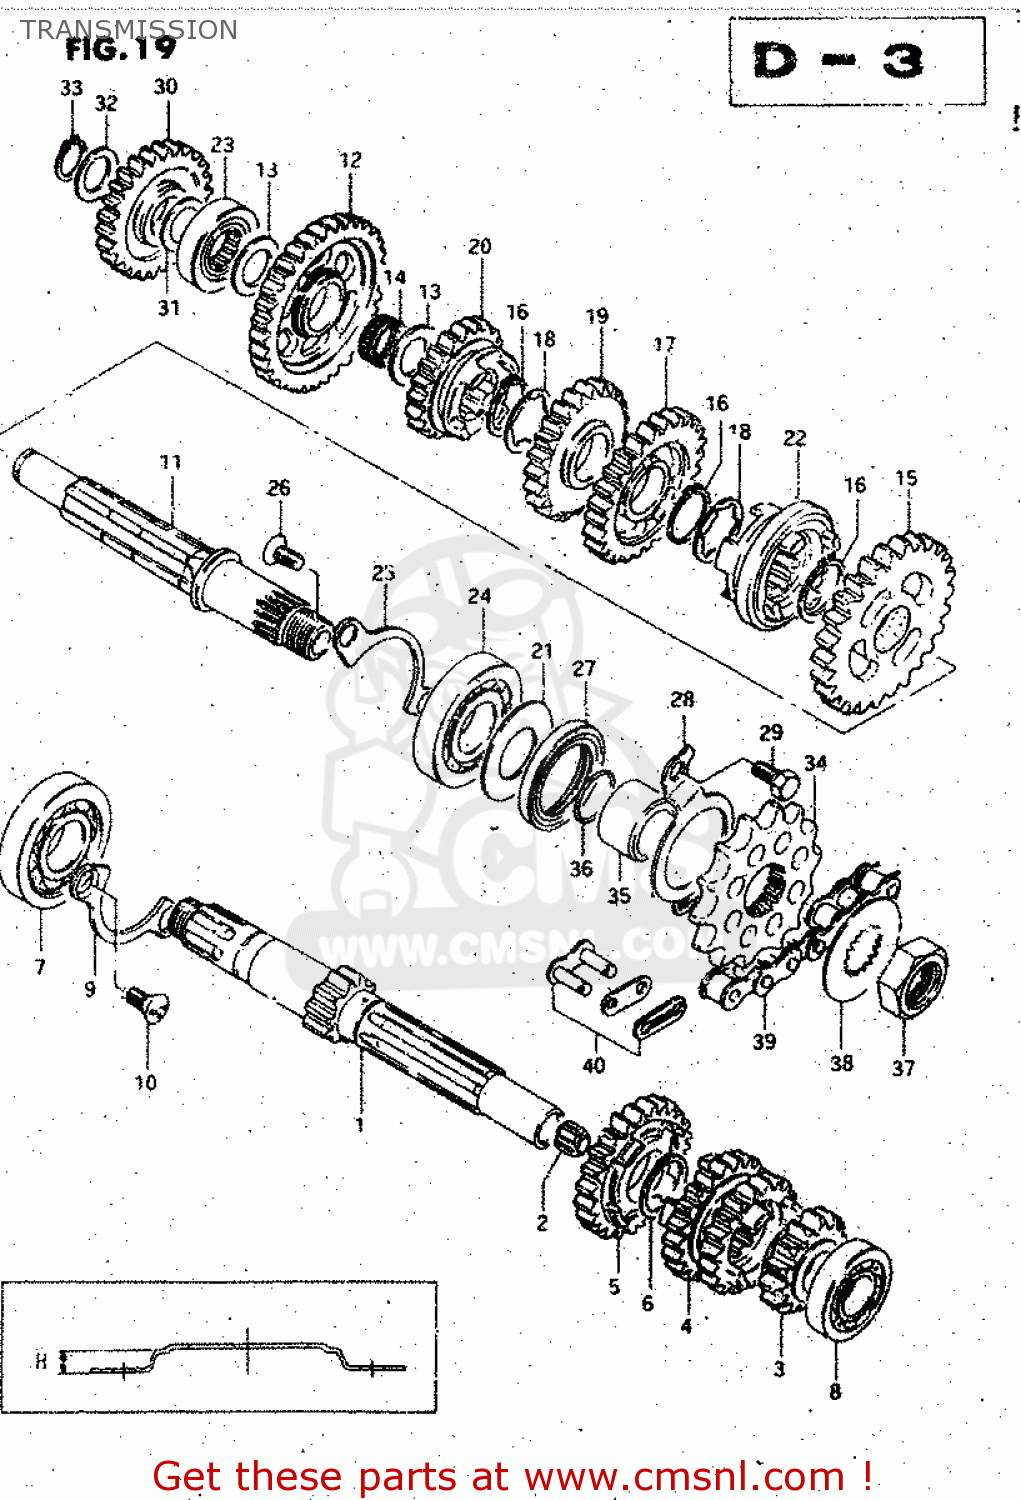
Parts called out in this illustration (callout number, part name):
1	SHAFT,COUNTER
2	BUSH
3	GEAR,SECOND DRIVE
4	GEAR,THIRD & FOURTH DRIVE,N
5	GEAR,FIFTH DRIVE
6	CIRCLIP
7	BEARING(20X47X14)
8	BEARING
9	RETAINER,DRIVE SHAFT BEARING
10	SCREW
11	SHAFT,DRIVE
12	GEAR,FIRST DRIVEN
13	WASHER
14	BEARING(15X19X7.8)
15	GEAR,SECOND DRIVEN
16	CIRCLIP
17	GEAR,THIRD DRIVEN
18	WASHER,LOCK
19	GEAR,FOURTH DRIVEN
20	GEAR,FIFTH DRIVEN
21	WASHER,OIL SEALING
22	WHEEL,SLIDING DOG
23	BEARING(15X33X12)
24	BEARING(20X47X14)
25	RETAINER,DRIVE SHAFT BEARING
26	SCREW
27	SEAL,OIL(27X40X6)
28	PLATE,DRIVESHAFT OIL
29	BOLT
30	GEAR,KICK STARTER IDLE(NT:26)
31	WASHER
32	WASHER
33	CIRCLIP,15MM
34	SPROCKET,ENGINE
35	SPACER
36	O RING(D:2.4,ID:19)
37	NUT
38	WASHER,LOCK
39	CHAIN ASSEMBLY,DRIVE
40	JOINT
